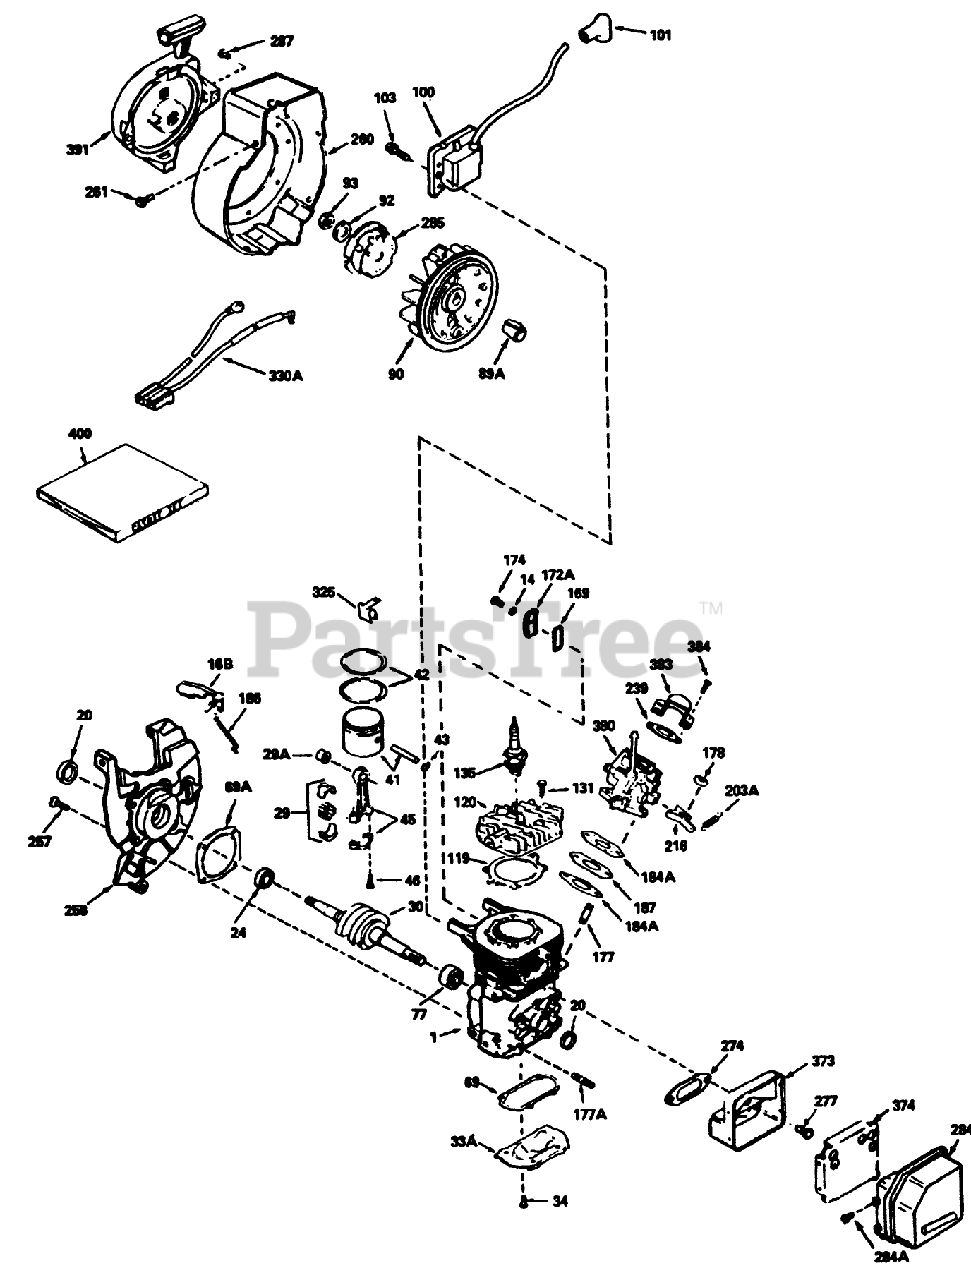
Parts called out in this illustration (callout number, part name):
1	Block Ass-y-Cylinder (Order short block if replacement is required)
16B	Vane-Air
20	Seal-Oil
24	Bearing-Ball
29	Needle Bearing and Liner Set (37 Needles)
29A	Bearing-Cartridge
30	Crankshaft
33A	Plate-Cover
34	Screw (T-25, 10-24 x 1/2)
41	Piston & Pin Ass-y (Incl. Ref. #43)
42	Ring Set
43	Ring-Retaning
45	Rod Ass-y-Connecting (Incl. Ref. #29, 29A, & 46)
46	Bolt-Rod, Connecting
69	Gasket-Plate, Cover
69A	Gasket-Cover, Cylinder
77	Bearing-Cartridge
89A	Blade (20 inch)
90	Flywheel
92	Washer-Belleville
93	Nut-Flywheel
100	Solid State
101	Cover-Spark Plug
103	Screw
119	Gasket-Head, Cylinder
120	Head-Cylinder
131	Screw (T-30, 1/4-20 x 3/4)
135	Spark Plug-Resistor (R C J 8Y)
169	Cover-Compression, Release
172A	Comp. Release Cover
174	Screw (T-25, 10-24 x 1/2)
178	Locknut
184	Gasket-Carburetor
184A	Gasket-Carburetor
186	Link-Governor
203	Spring-Governor
203A	Spring-Governor
216	Lever-Adjusting, Rpm
239	Gasket-Cleaner, Air
257	Screw (T-30, 1/4-20 x 5/8)
258	Base Ass-y-Blower Housing (Incl Ref. #20)
260	Housing-Blower
261	Screw (1/4-20 x 1/2)
274	Gasket-Exhaust
277	Screw (T-30, 1/4-20 x 5/8)
284	Cover-Muffler
284A	Cover-Muffler
285	Cup-Starter
287	Rivet-Pop
325	Clip-Wire
330	Harness-Wire
330A	Harness-Wire
373	Base-Muffler
374	Baffle-Muffler
380	Carburetor (Incl. Ref. #184A)
383	Baffle-Carburetor
391	Starter-Rewind
400	Gasket Set
